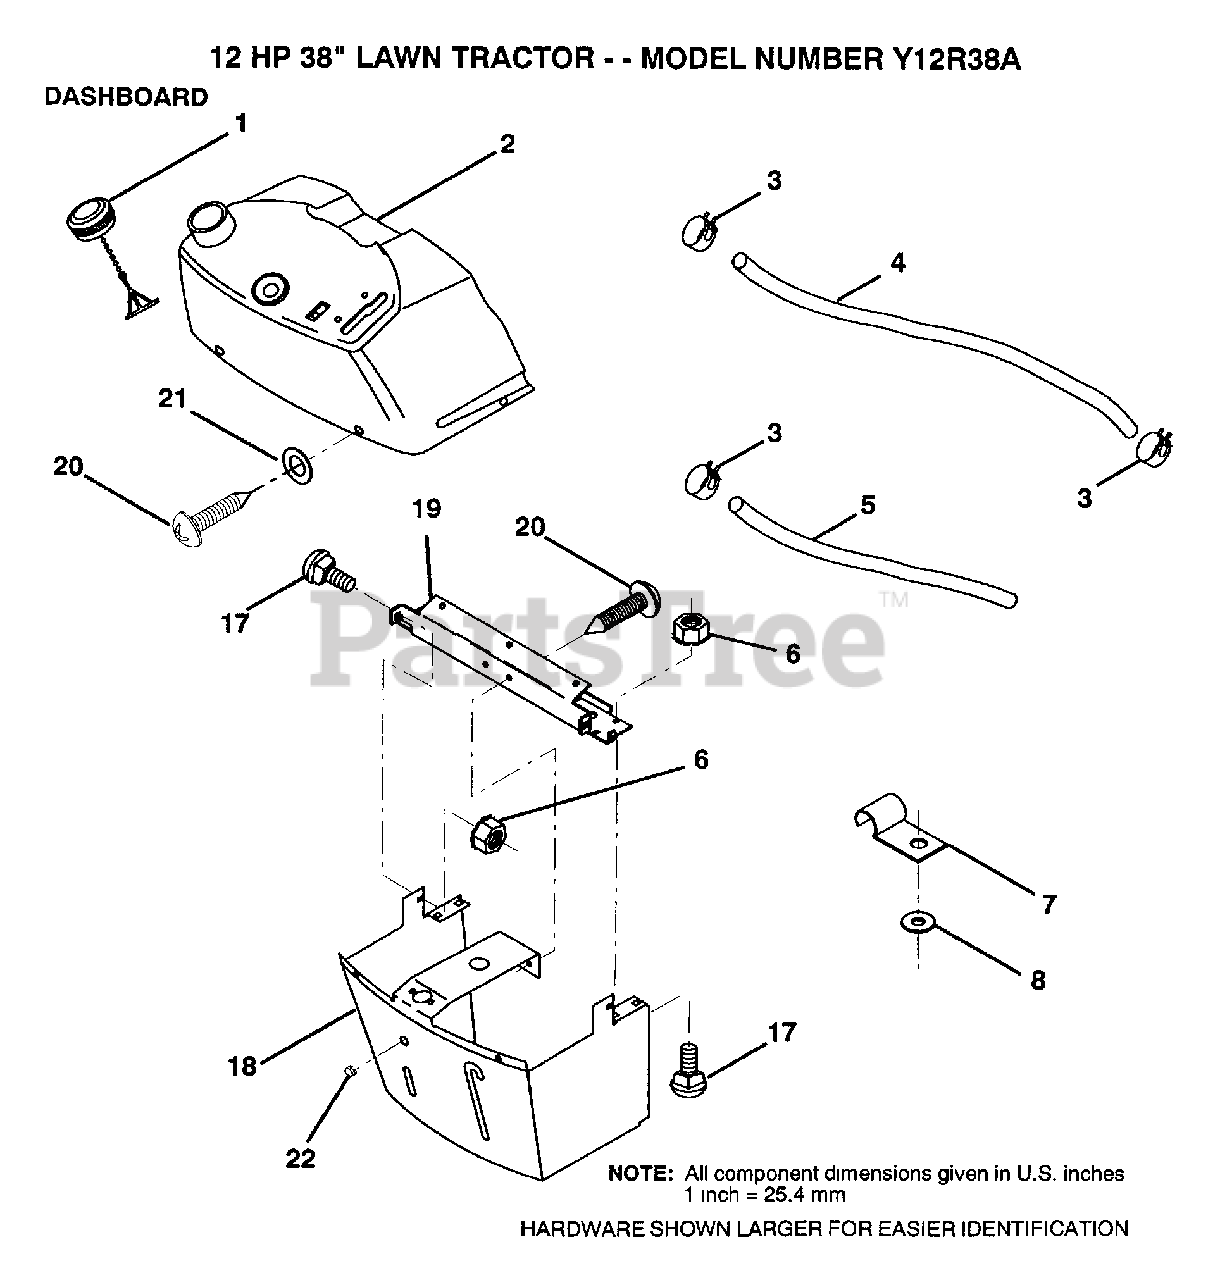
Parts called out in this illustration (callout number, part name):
3	HOSE CLAMP
5	FUEL LINE T
6	NUT
7	CLIP T
8	WASHER PM
17	BOLT
18	SUPT ASM DASH
19	CROSS BRACE
22	PLUG DOME
